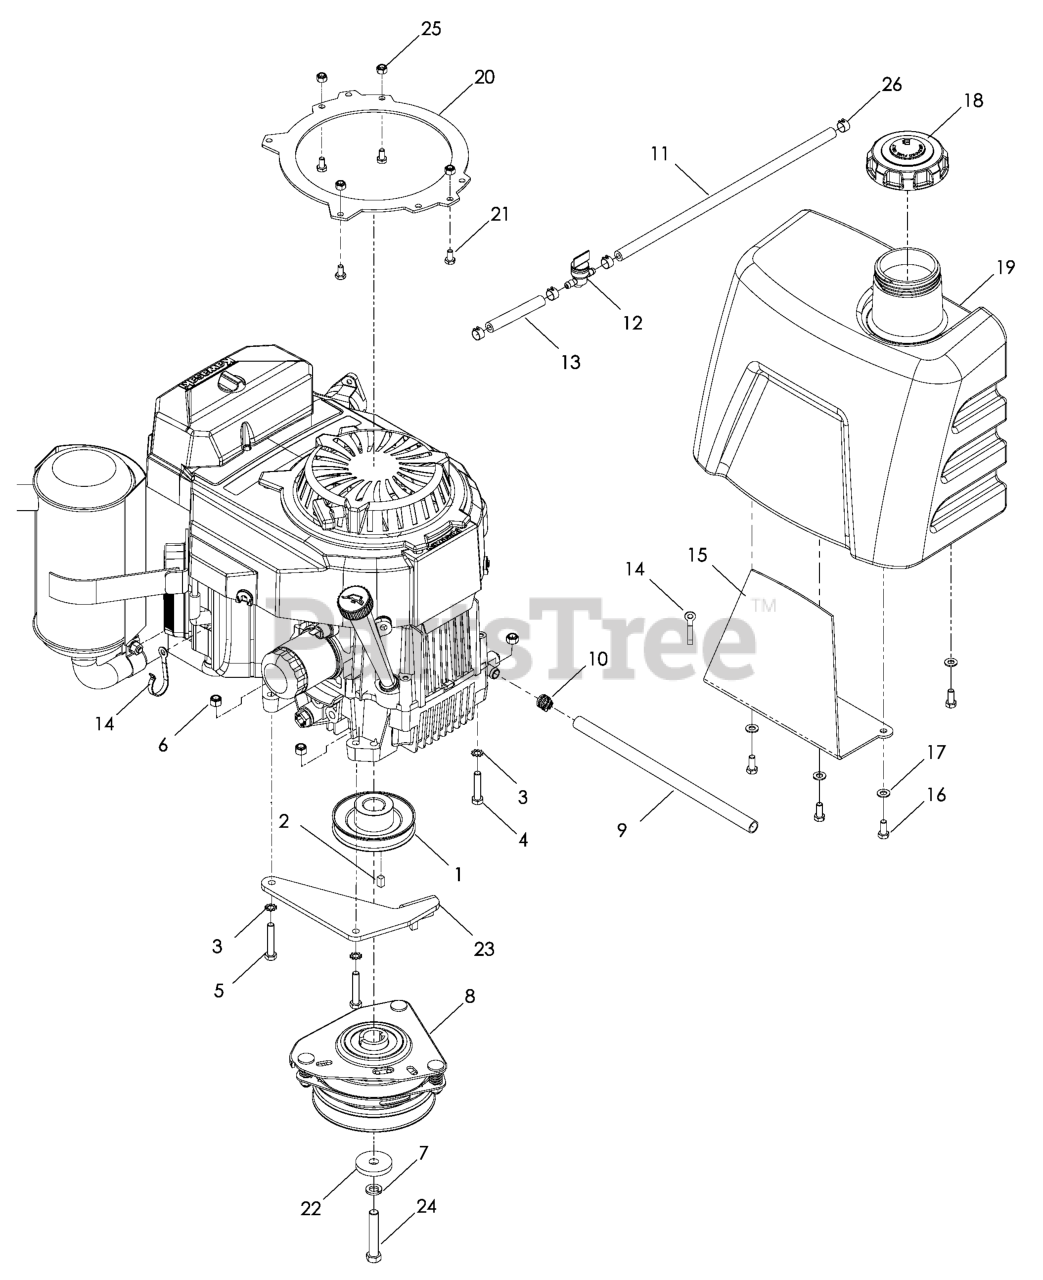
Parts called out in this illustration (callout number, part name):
1	PULLEY - ENGINE
2	SQUARE KEY - 1/4 X .5
3	WASHER 5/16 EXT STAR
4	CAPSCREW 5/16 X 1/1/2 HEX HEAD
5	HCS 5/16C X 1 3/4
6	NUT 5/16 NYLOC
7	WASHER 7/16 LOCK
8	CLUTCH.ELECTRIC.LT.48"*
9	OIL DRAIN HOSE
10	HOSE CLAMP T-1865
11	FUEL LINE 13"
12	FUEL VALVE
13	FUEL LINE 3"
15	PLATE ID, ORANGE
16	HCS 5/16C X 3/4
17	FLAT WASHER 5/16 SAE
18	FUEL CAP ANTI-SPLASH
19	FUEL TANK
20	ADAPTER - RECOIL
21	HCS 1/4-20.
22	SPINDLE WASHER
23	CLUTCH STOP
24	BOLT 7/16F X 2 1/2
25	NUT.1/4-20.HEX.NYLOC.ZD
26	HOSE CLAMP
